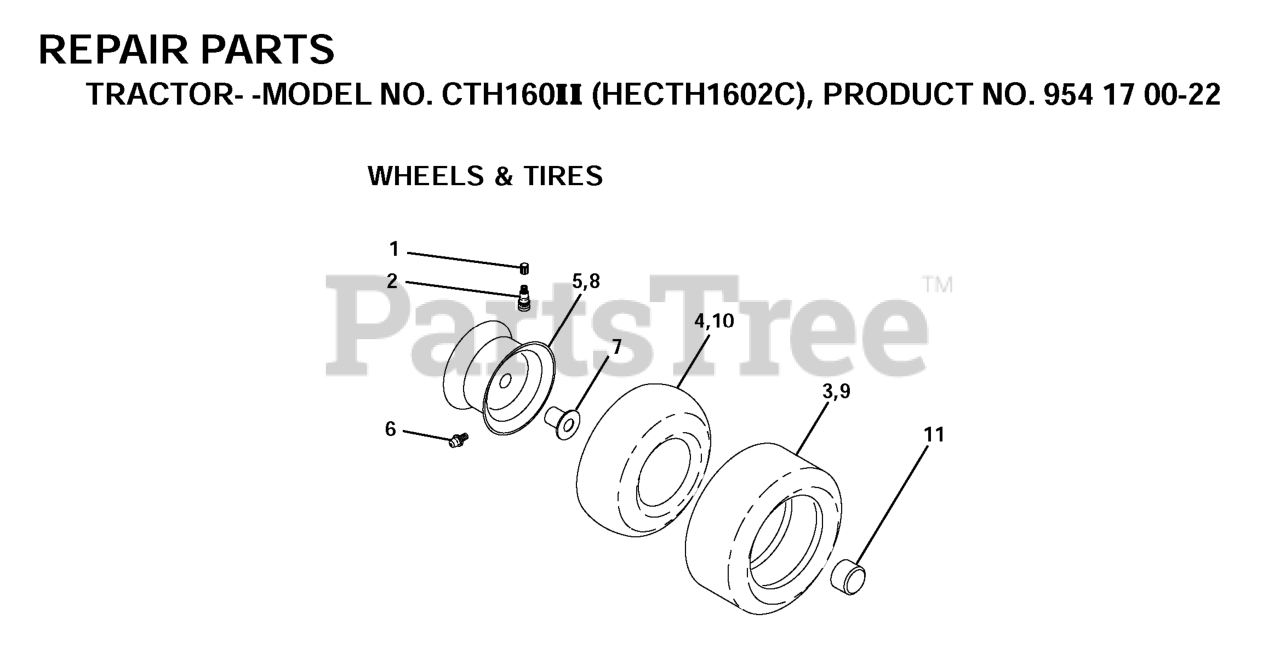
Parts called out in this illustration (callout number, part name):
2	VALVE STEM LT
3	TIRE HEAVY DUTY
4	TUBE.5.3/4.5/6
5	RIM ASM 6" FRONT SILVER
6	FITTING LT
7	BEARING T
8	RIM ASM 8" REAR SILVER
9	TIRE.20X8-8.TURF.SAVER
10	TUBE
11	CAP, AXLE BLK
